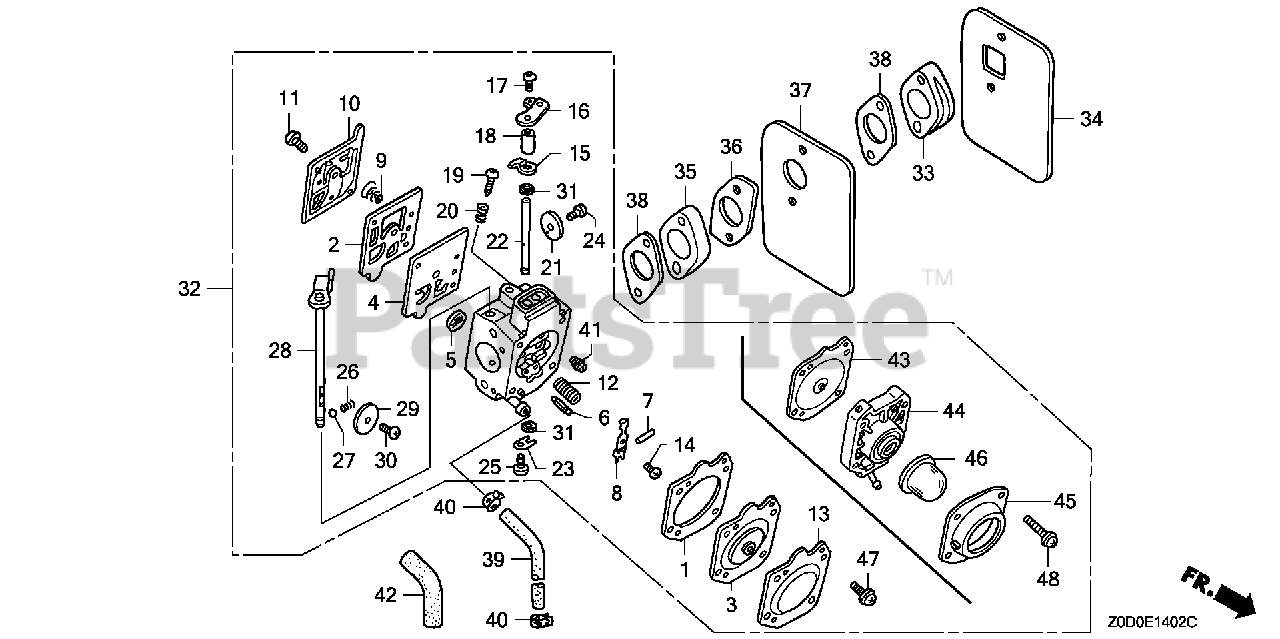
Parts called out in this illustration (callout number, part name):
1	GASKET, METERING DIAPHRAGM
2	GASKET, PUMP
3	DIAPHRAGM ASSY., METERING (CARBURETOR NO.)
4	DIAPHRAGM, PUMP
5	SCREEN, INLET
6	VALVE, INLET NEEDLE
7	PIN, METERING LEVER
8	LEVER, METERING
9	SPRING, PUMP
10	COVER, PUMP (CARBURETOR NO.)
12	SPRING (CARBURETOR NO.)
13	COVER, METERING DIAPHRAGM (CARBURETOR NO.)
14	SCREW (CARBURETOR NO.)
15	STOPPER, THROTTLE LEVER
16	LEVER, THROTTLE (CARBURETOR NO.)
17	SCREW, VALVE
18	SPACER, THROTTLE LEVER
19	SCREW, IDLE ADJUSTING
21	VALVE, THROTTLE
22	SHAFT, THROTTLE
23	CLIP, THROTTLE SHAFT
24	SCREW, VALVE
25	SCREW ASSY.
28	SHAFT ASSY., CHOKE (CARBURETOR NO.)
29	VALVE, CHOKE (CARBURETOR NO.)
32	CARBURETOR ASSY. (HDA 206B)
32	CARBURETOR ASSY. (HDA 206D)
32	CARBURETOR ASSY. (HDA 206E)
33	INSULATOR, CARBURETOR
34	GASKET, INSULATOR
35	INSULATOR B, CARBURETOR
36	GASKET B, INSULATOR
37	PLATE, INSULATOR
38	GASKET, CARBURETOR
41	JET (#50)
41	JET (#52) (CARBURETOR NO.)
47	SCREW ASSY. (CARBURETOR NO.)
